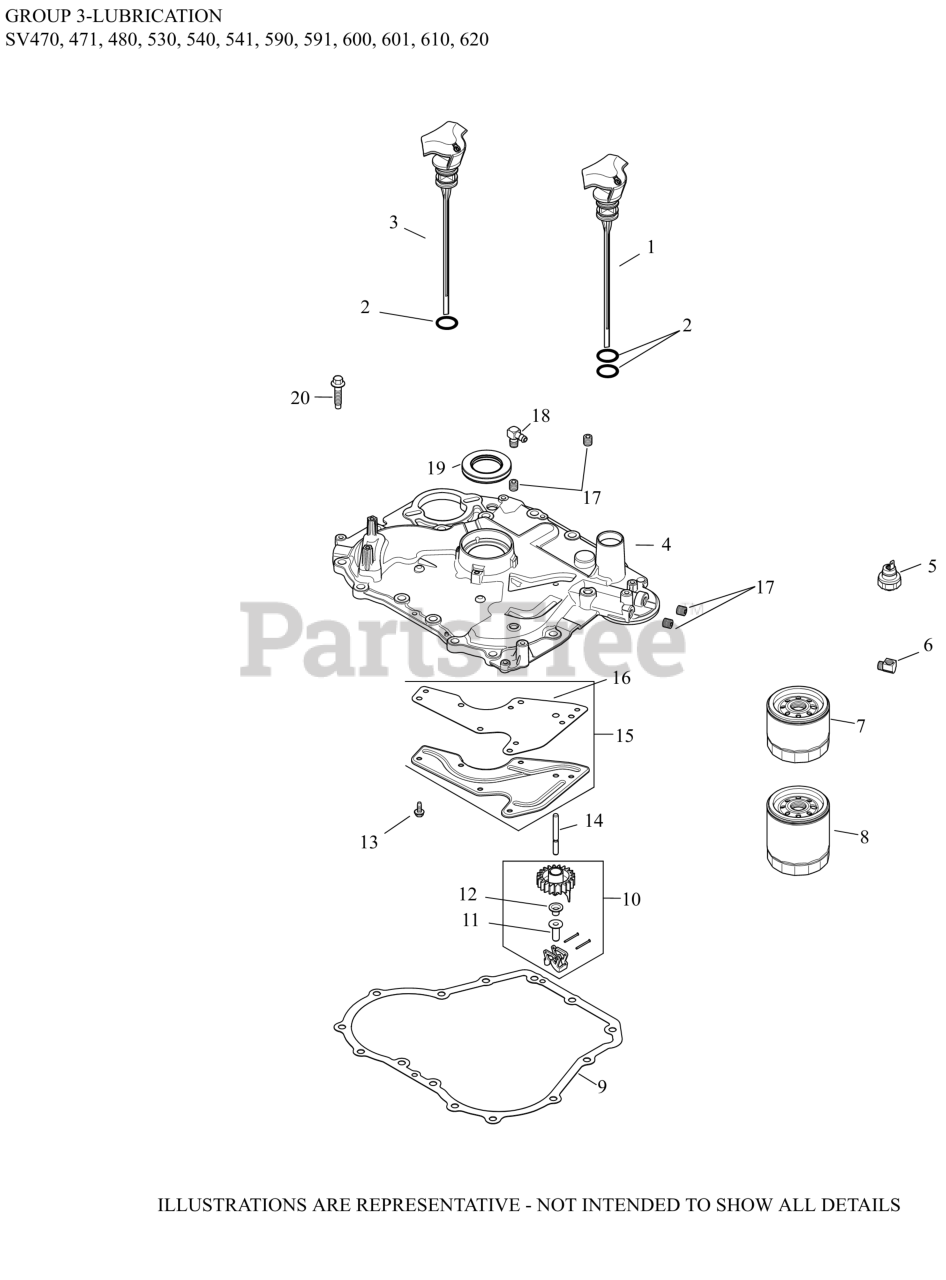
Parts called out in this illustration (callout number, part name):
1	DIPSTICK, BLADE & CAP ASSY-USE 20 040 08
3	BLADE, DIPSTICK ASSEMBLY
4	KIT, CLOSURE PLATE ASSEMBLY
4	CLOSURE PLATE ASSY-USE 20 009 35-S
7	OIL FILTER
9	GASKET, CLOSURE PLATE-USE 20 041 21-S
10	KIT, GOVR GEAR ASSY-USE 25 310 08-S
11	PIN, GOVERNOR REGULATING
13	SCREW, FLG THD FRM M5X0.8X13
14	SHAFT, GOVERNOR CROSS
15	KIT, OIL PASSAGE COVER
16	GASKET, OIL PASSAGE
19	SEAL, OIL
20	HEX FLANGE SCREW-USE 25 086 421-S
